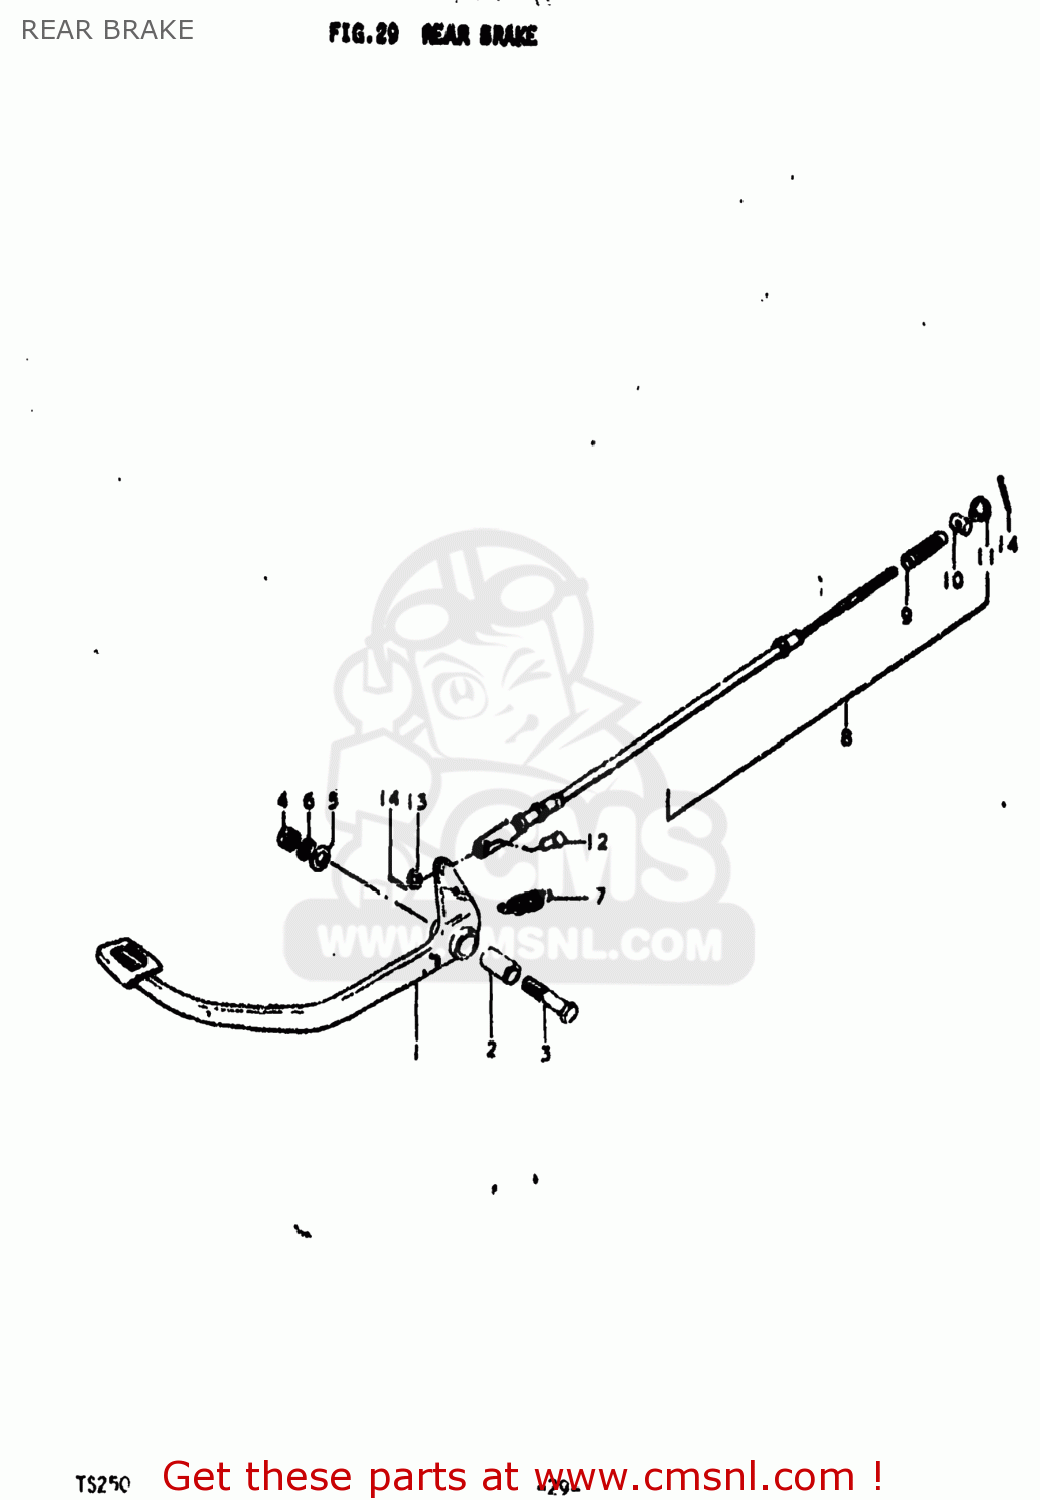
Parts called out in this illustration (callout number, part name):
1	PEDAL,BRAKE
2	SPACER(10.5X16X30)
3	BOLT
4	NUT
5	WASHER
6	LOCK WASHER
7	SPRING
8	CABLE ASSY,RR BRAKE
9	SEAL,DUST
10	PIN
11	NUT
12	PIN(L:17.5)
13	WASHER
14	PIN
